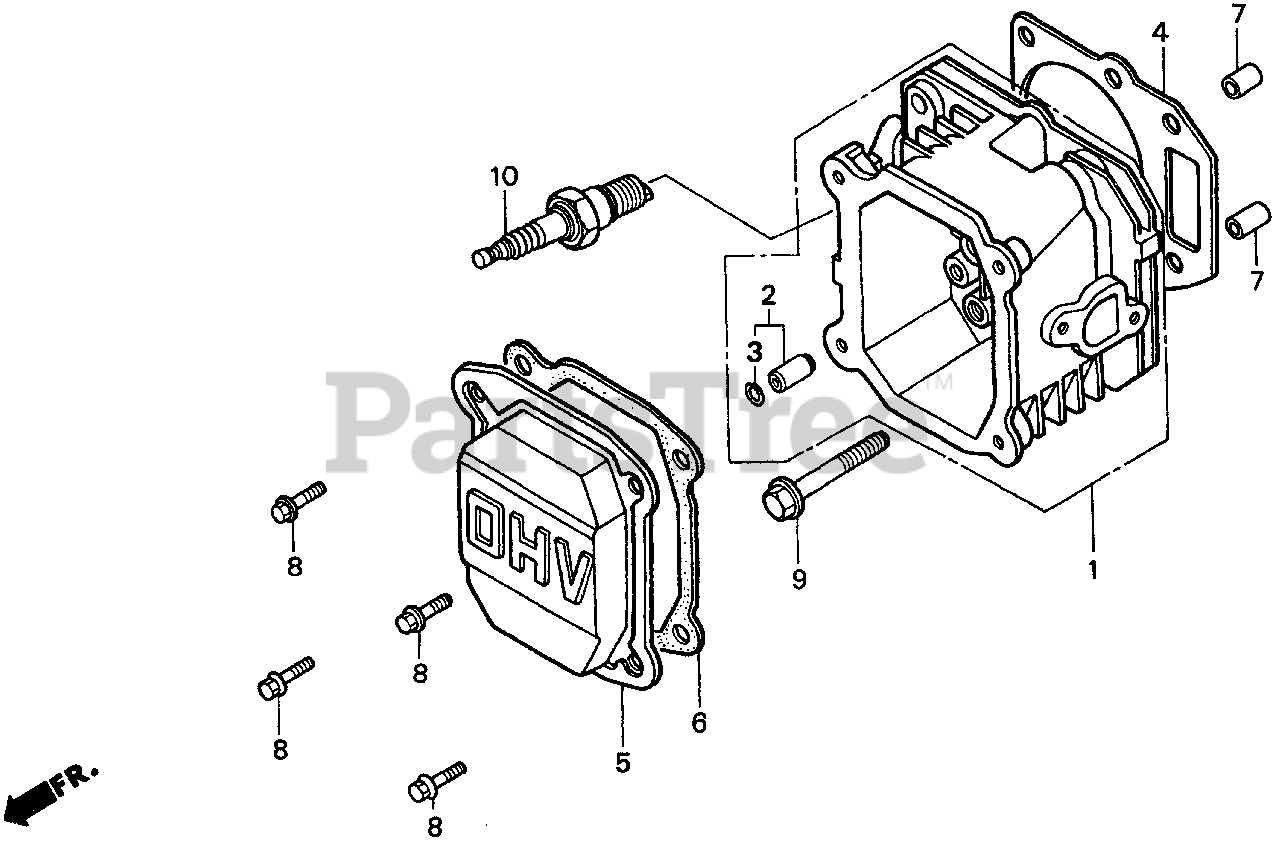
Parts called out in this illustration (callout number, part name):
1	CYLINDER HEAD (USA)
2	GUIDE, EX. VALVE (OS)
3	CLIP, VALVE GUIDE
4	GASKET, CYLINDER HEAD
5	COVER, HEAD
6	GASKET, HEAD COVER
7	PIN A, DOWEL (10X16)
8	BOLT, FLANGE (6X14)
9	BOLT, FLANGE (8X50)
10	SPARK PLUG (BPR4ES) (NGK)
10	SPARK PLUG (BPR5ES) (NGK)
10	SPARK PLUG (BPR6ES) (NGK)
